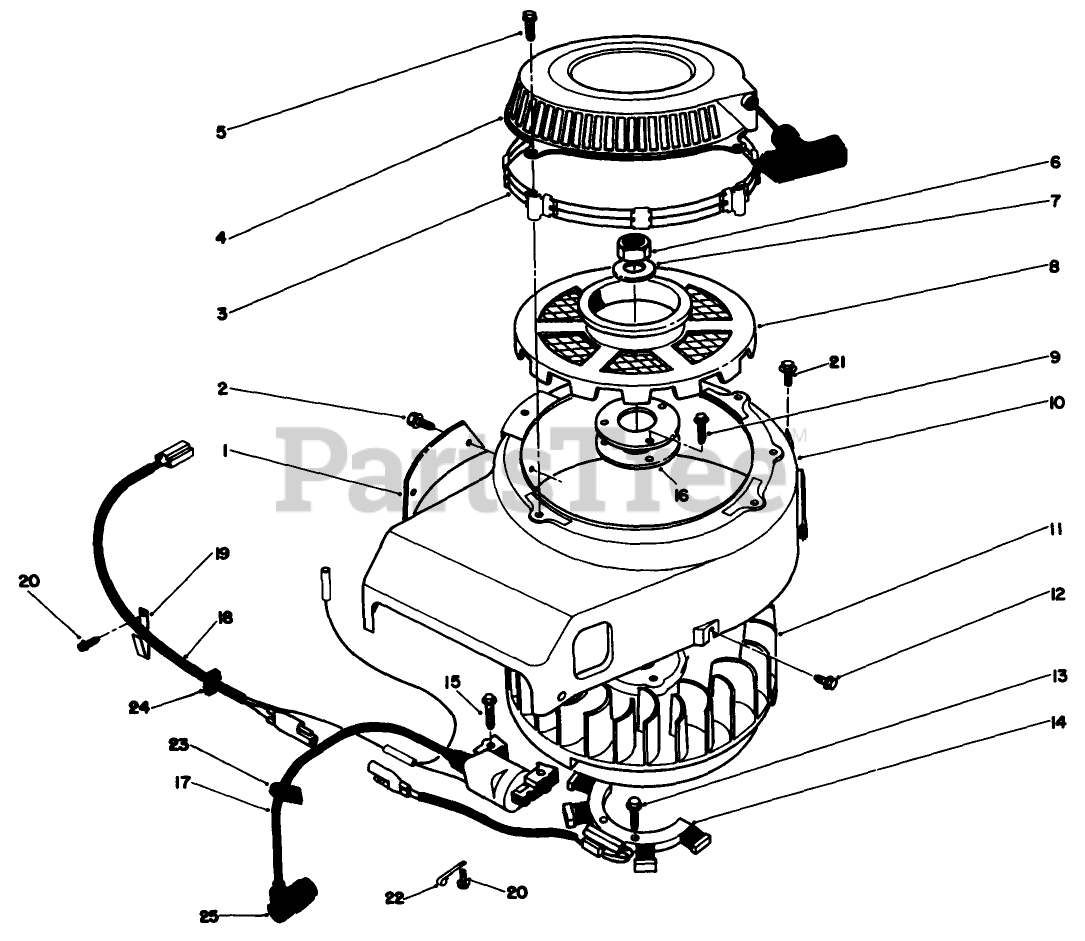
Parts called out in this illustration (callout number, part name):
4	Recoil Starter ASM
5	Bolt-Flanged (6X35)
9	Bolt-Flanged (8X12)
10	Housing-Fan
11	Flywheel
12	BOLT-FLANGED (6X10)
18	Harness
20	Bolt-Flanged (6X10)
21	Bolt-Flanged (6X14)
23	Grommet
24	Grommet
25	Cap-Spark
